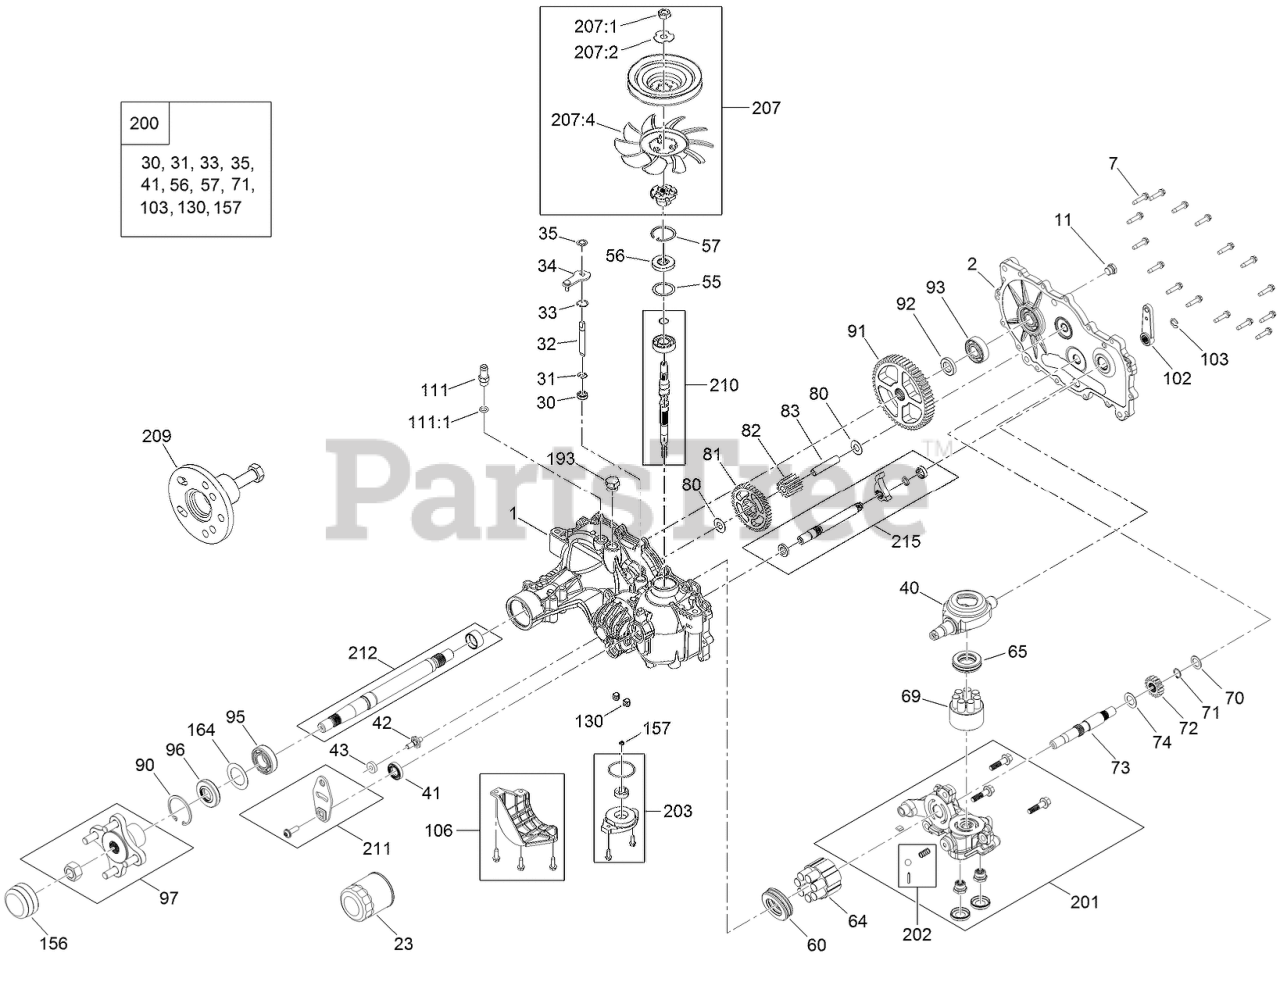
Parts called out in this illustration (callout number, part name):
1	RH MAIN HOUSING KIT
2	RH SIDE COVER KIT
7	SCREW-HHF
23	ELEMENT-OIL FILTER, HYD
30	SEAL-LIP
31	RING-RETAINING, EXTERNAL
32	ROD-BYPASS
33	RING-RETAINING, INTERNAL
35	RING-RETAINING, EXTERNAL
40	SWASHPLATE-TRUNNION
41	SEAL-LIP
43	PUCK-FRICTION
55	SPACER
56	SEAL-LIP
57	RING-RETAINING
60	BEARING-THRUST
64	CYLINDER BLOCK ASM KIT
65	BEARING-THRUST
69	PUMP BLOCK ASM
70	WASHER-FLAT
71	RING-RETAINING
72	GEAR-14T
73	SHAFT-MOTOR
74	WASHER
80	WASHER
81	GEAR-45T
82	GEAR-11T
83	PIN-JACKSHAFT
90	RING-RETAINING
91	GEAR-54T
92	SPACER
93	BEARING KIT
95	BEARING-BALL
97	HUB KIT
102	HANDLE-BRAKE
103	RING-RETAINING, EXT
106	FILTER GUARD KIT
111	ADAPTER-STRAIGHT
111:1	O-RING
130	TUBE-CHARGE
156	COVER-NUT, AXLE
157	GEROTOR SEAL KIT
164	SPACER
200	SEAL KIT
201	RH CHARGE CENTER SECTION KIT
202	CHARGE RELIEF KIT
203	CHARGE KIT
207	FAN AND PULLEY KIT
207:1	NUT-HJ
207:2	WASHER-SLOTTED
207:4	FAN 7.0 X 10 BLADE
210	INPUT SHAFT KIT
211	CONTROL ARM KIT
212	AXLE SHAFT KIT
215	INBOARD KIT
